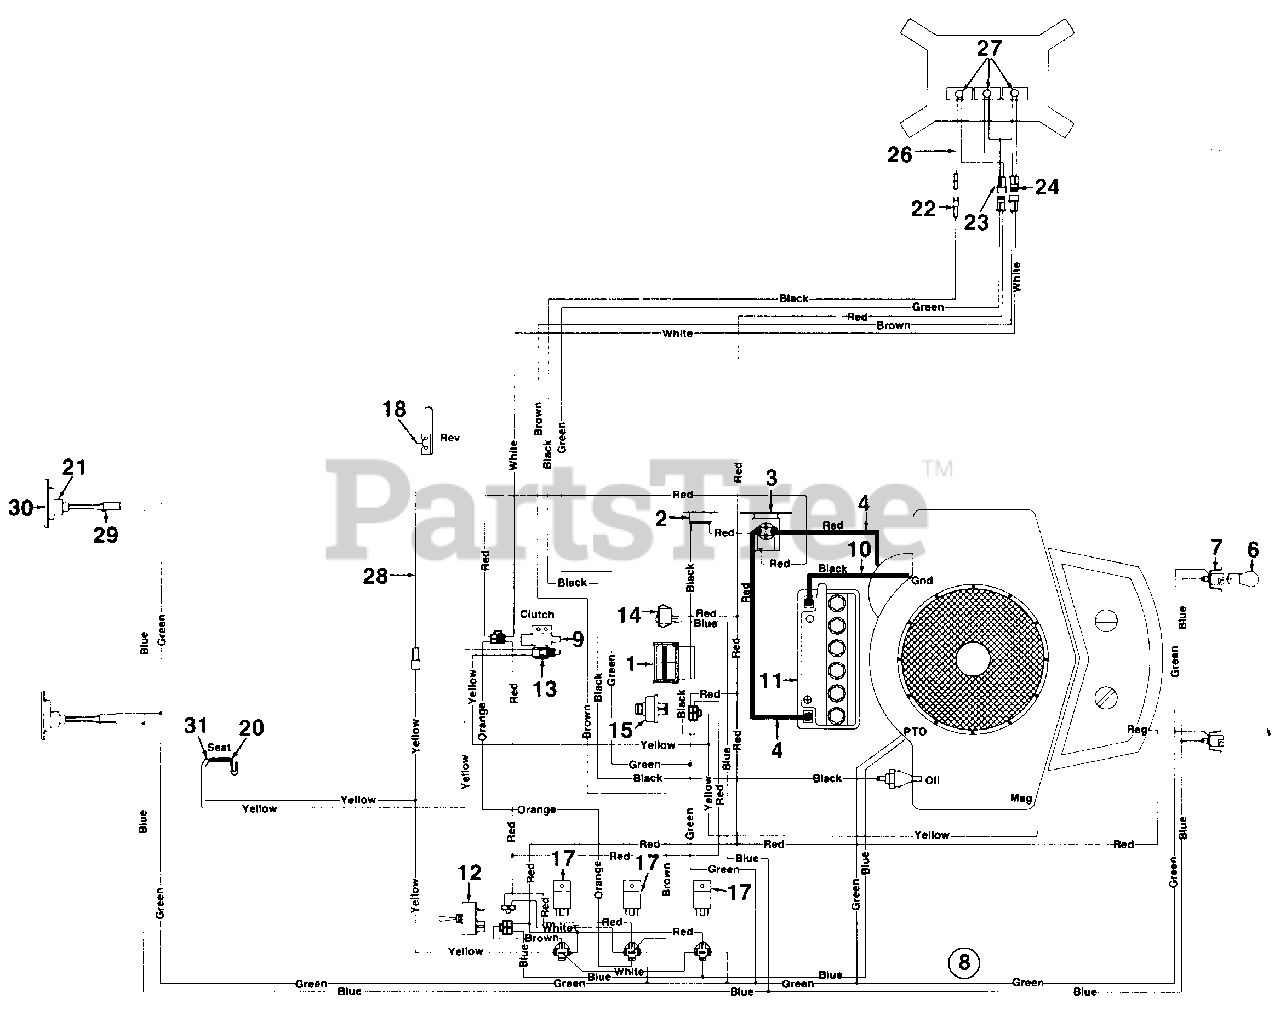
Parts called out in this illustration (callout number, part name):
1	Ammeter
2	Circuit Breaker
3	Solenoid
4	Wire
6	Bulb
7	Socket
8	Wire Harness
9	Safety Switch (Clutch)
10	6 Ga. Black Wire
11	Battery (275 Cold Crank Amps)
12	Switch (PTO)
13	Safety Switch (Clutch)
14	Light Switch
15	Ignition Switch
17	Relay
18	Spring Lever
20	Safety Switch (Seat)
21	Taillight
22	Connector
23	Connector
24	Connector
26	Wire Harness
27	Bulb
28	Transmission Ext. Wire
29	Taillight Harness
31	Safety Switch (Seat)
